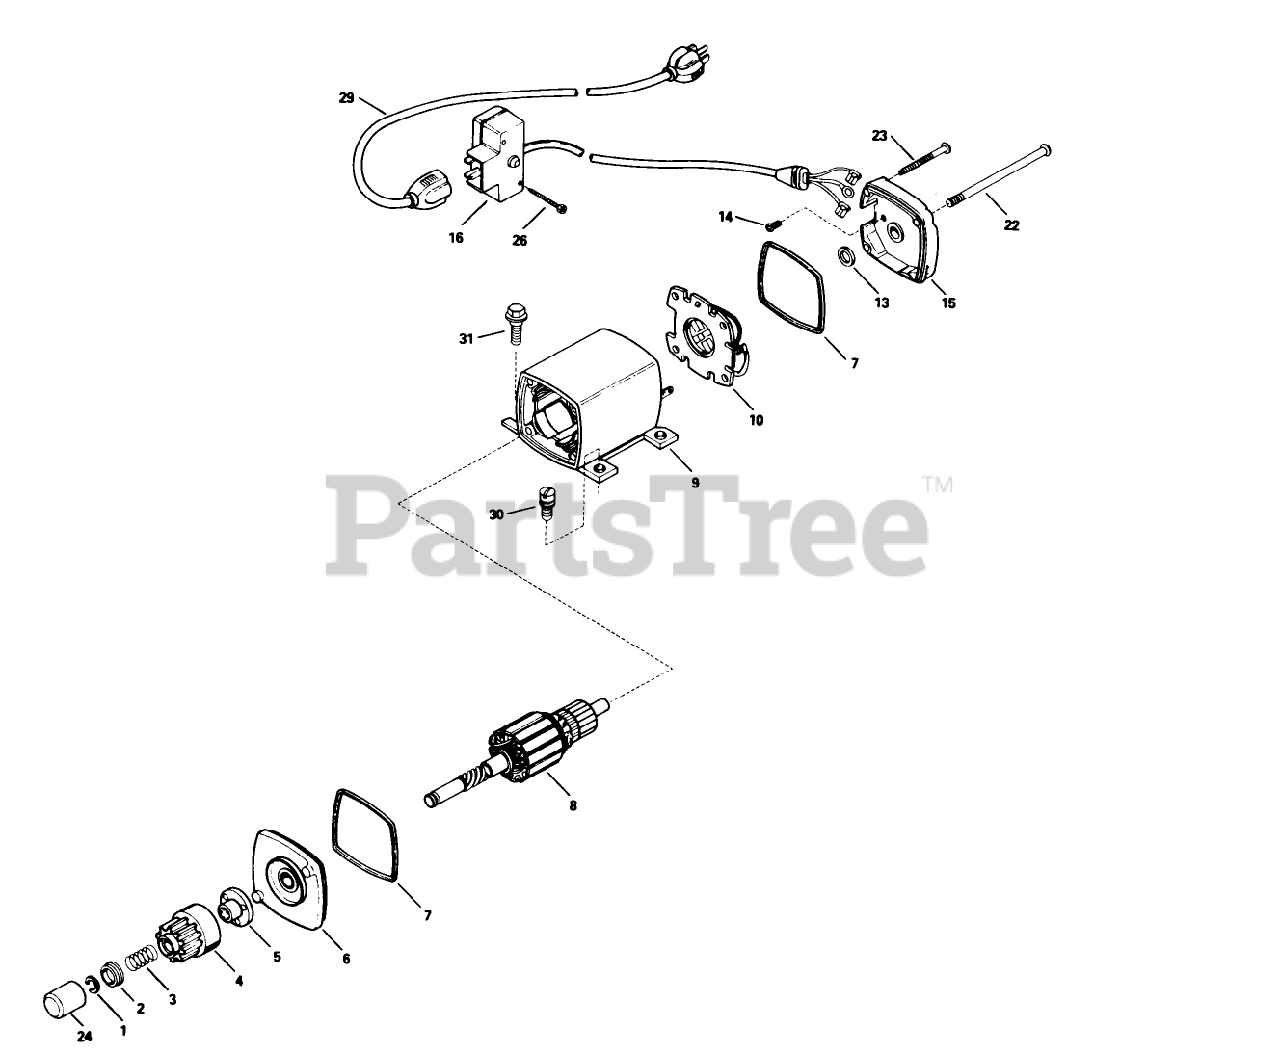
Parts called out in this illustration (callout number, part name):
1	Ring-Retainer
2	Retainer-Spring
3	Spring-Anti Drift
4	Gear
5	Nut-Engaging
6	Cap Assembly-Cap End (Incl. Ref. #7)
7	O-Ring
8	Armature
9	Housing Assy.
10	Card ASM
13	Washer-Thrust
14	Screw-Ground
15	Cap Assembly (Incl. Ref. #7)
16	Box Assembly-Switch (Incl. Ref. #26)
22	Bolt-Case
23	Screw-Ground
24	Cover-Dust
26	Screw
29	Cord-Extension
30	Screw
31	Screw (1/4-20x1/2)
